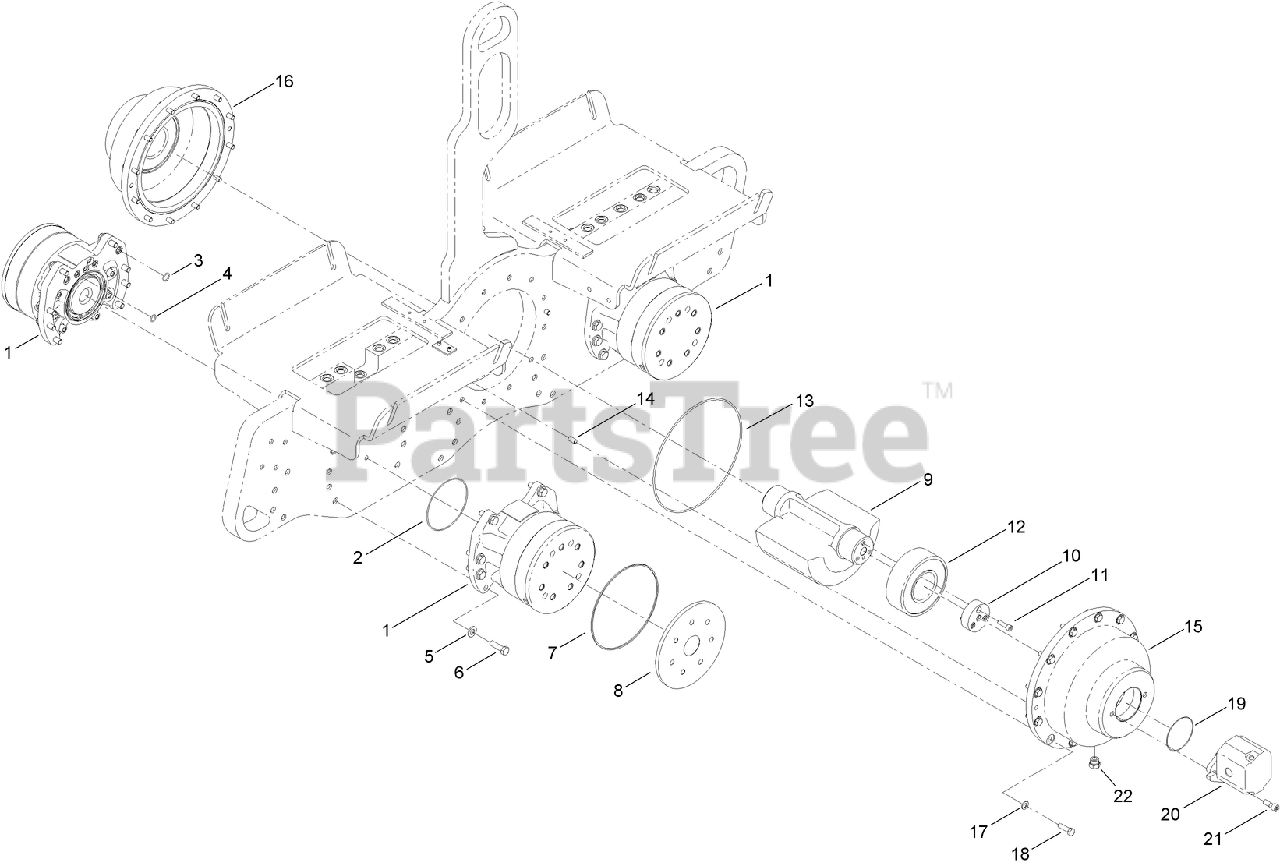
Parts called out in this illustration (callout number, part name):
1	HYD MOTOR ASM
2	O-RING
3	O-RING
4	O-RING
5	WASHER-FLAT
6	SCREW-HH
7	SEAL-LIP, BLUE
8	COVER-PROTECTOR
9	WEIGHT-COUNTER, ECCENTRIC
10	SHAFT-EXTENSION, ECCENTRIC
11	SCREW-HSH
12	BEARING-ROLLER
13	O-RING
15	CAP-MOTOR, ECCENTRIC
16	CAP-END, ECCENTRIC
17	WASHER-FLAT
18	SCREW-HH
19	O-RING
20	HYD GEAR MOTOR ASM
21	SCREW-HSH
